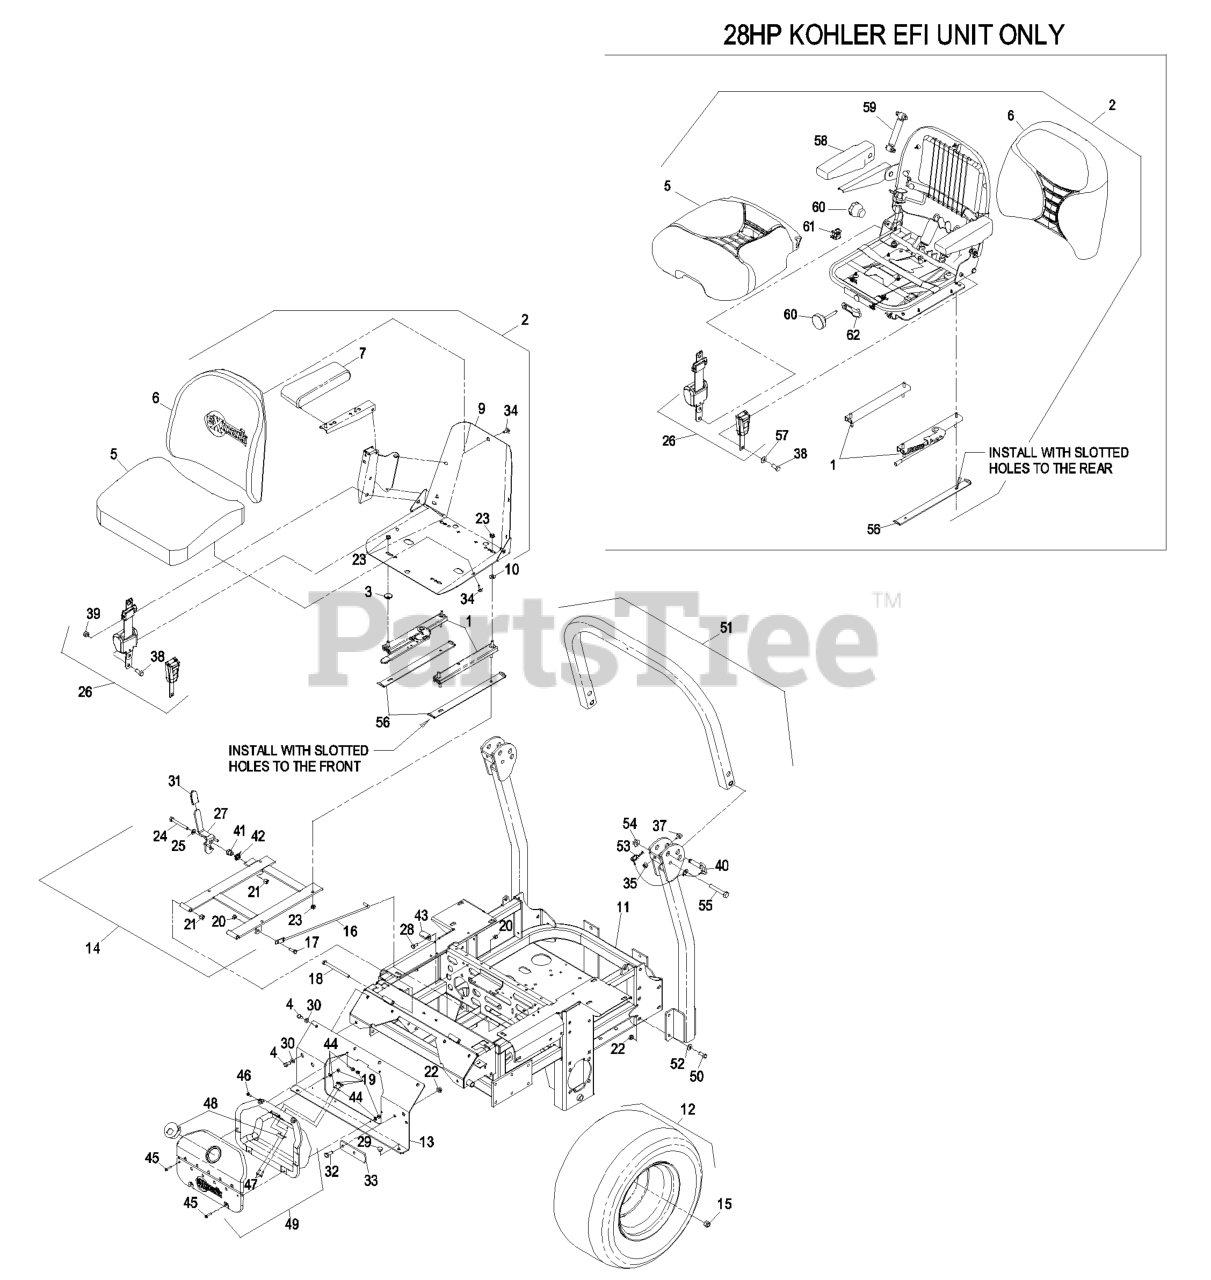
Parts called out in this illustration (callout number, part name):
1	TRACK-SEAT
2	KIT,SEAT W/ARMREST ADJ.
3	SPACER-TRACK
4	SCREW-HH
5	CUSHION,SEAT BOTTOM
6	CUSHION,SEAT BACK
7	CUSHION,ARMREST RH
9	FRAME-SEAT
10	WASHER-FLAT
11	ASM,MAINFRAME W/DECAL
12	WHEEL AND TIRE ASM
13	ASM, CONSOLE W/DECALS
14	ASM,SEAT FRAME
15	NUT-LUG
16	ROD-HOLDUP, SEAT
17	SCREW-HH
18	SCREW-HH
19	NUT-LOCK, NI
20	NUT-LOCK, NI
21	NUT-LOCK, NI
22	NUT-HHF, WHIZ
24	SCREW-HH
25	WASHER-FLAT
26	RETRACTABLE SEATBELT KIT
27	LATCH ASM
28	SCREW-HH
30	WASHER-PLAIN
31	GRIP-LEVER
32	SCREW-HH
33	STOP-BRAKE, PARK
34	BOLT-SEAT
35	NUT-LOCK, NI
36	SCREW-HH
37	BUMPER-RUBBER
38	SCREW-HH
39	NUT-LOCK
40	PIN-FOLD, ROPS
41	BUSHING-LATCH, SEAT
42	SPRING-TORSION
43	CATCH-LATCH, SEAT
44	WASHER-FLAT
46	SCREW-HEAD, TRUSS
47	SCREW-PPH
48	LATCH,CUBBY
49	ASM,CUBBY
50	SCREW-HH
51	KIT, ROPS LZ >510,000
52	WASHER-BELLEVILLE
53	HAIRPIN
55	SCREW-HH
56	STOP-SEAT
57	WASHER-SPRING
58	PAD-ARMREST
59	SHOCK ABSORBER KIT
60	KNOB KIT
61	SWITCH-BAIL
62	WEIGHT INDICATOR KIT
